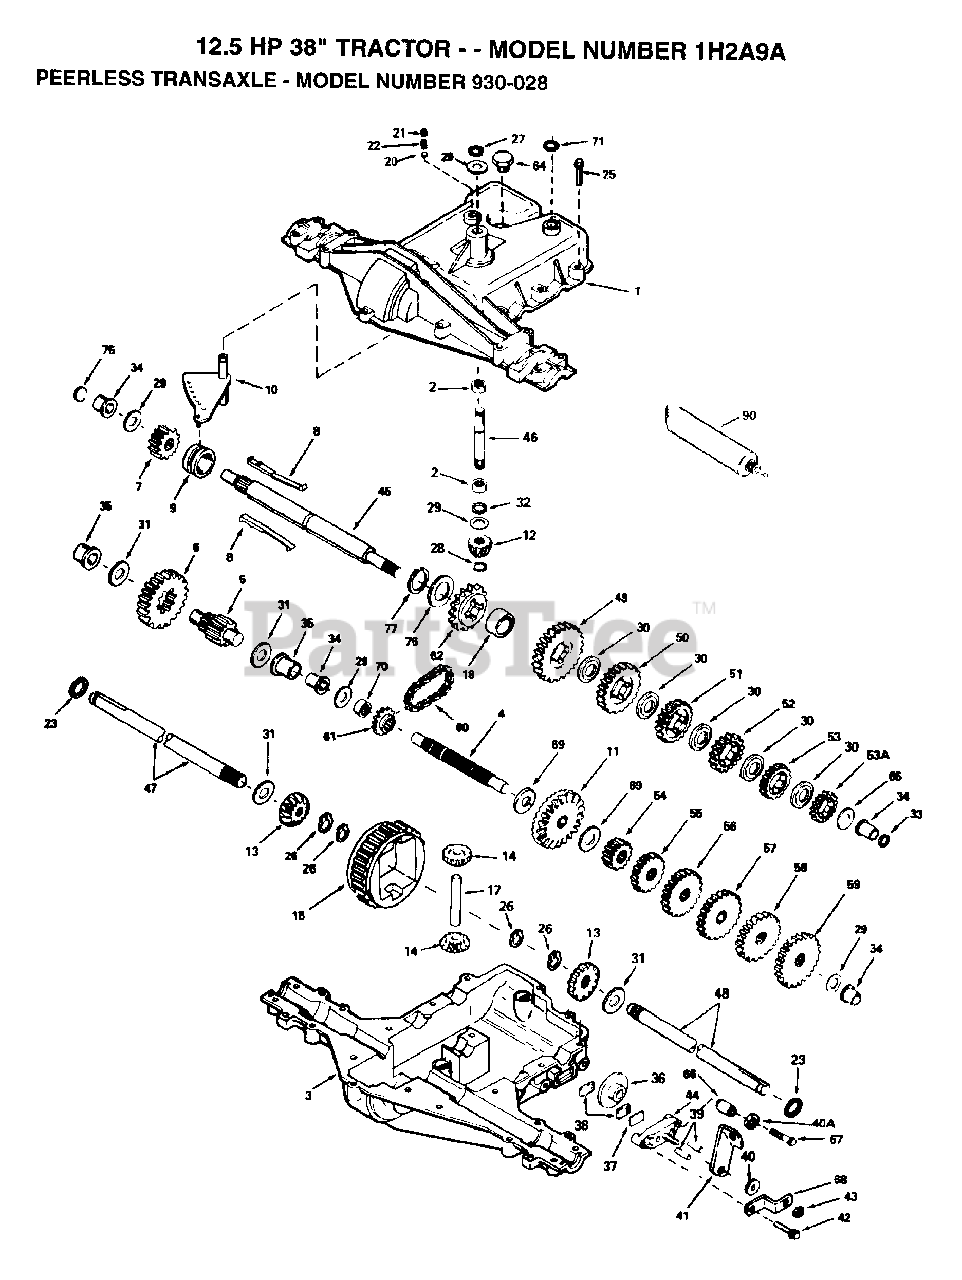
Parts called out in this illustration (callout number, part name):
1	COVER, TRANSAXLE
2	BEARING, NEEDLE
3	CASE, TRANSAXLE
4	SHAFT, COUNTER
5	SHAFT, PINION ASSEMBLY, OUTPUT
6	GEAR, OUTPUT
7	GEAR, SPUR, 15 TEETH
9	COLLAR, SHIFTER
10	ROD & FORK ASSY, SHIFT
11	GEAR, BEVEL, 42 TEETH
12	BEVEL PINION, INPUT
13	GEAR, BEVEL
14	GEAR, BEVEL, PINION
18	SPACER, NEUTRAL
20	BALL STEEL, 5/16" DIA.
21	SCREW, 3/8-16 X 3/8"
25	SCREW, 1/4-20 X 1-1/4
26	RING RETAINER
27	RING, RETAINER
28	RETAINING RING
29	WASHER THRUST
30	WASHER THRUST
33	SEAL, SQUARE CUT
34	BUSHING, FLANGED
35	BUSHING, FLANGED
36	DISK, BRAKE
37	PLATE BRAKE PAD
40	WASHER, FLAT
40A	WASHER FLAT
41	LEVER BRAKE
42	SCREW, 1/4-20 X 1-1/4
43	LOCKNUT 5/16-24
44	HOLDER BRAKE PAD
45	SHAFT, BRAKE, 4 KEYED
46	SHAFT, INPUT
49	GEAR, SPUR, 37 TEETH
50	GEAR, SPUR, 35 TEETH
51	GEAR, SPUR, 30 TEETH
52	GEAR, SPUR, 25 TEETH
53	GEAR, SPUR, 22 TEETH
53A	GEAR, SPUR, 19 TEETH
54	GEAR, SPUR, 12 TEETH
55	GEAR, SPUR, 15 TEETH
56	GEAR, SPUR, 20 TEETH
57	GEAR, SPUR, 25 TEETH
58	GEAR, SPUR, 28 TEETH
59	GEAR, SPUR, 31 TEETH
60	CHAIN, ROLLER
61	SPROCKET 9T
62	SPROCKET 18T (REV)
64	PLUG, THRDED, 9/16-18
65	WASHER, THRUST
67	SCREW FLNG HEX 1/4-20 X 2-1/4
68	BRKT BRAKE LEVER
69	WASHER THRUST
71	SEAL SQUARE CUT
76	WASHER, THRUST
77	RING, RETAINING
90	GREASE BENTONITE, 32 OZ.
